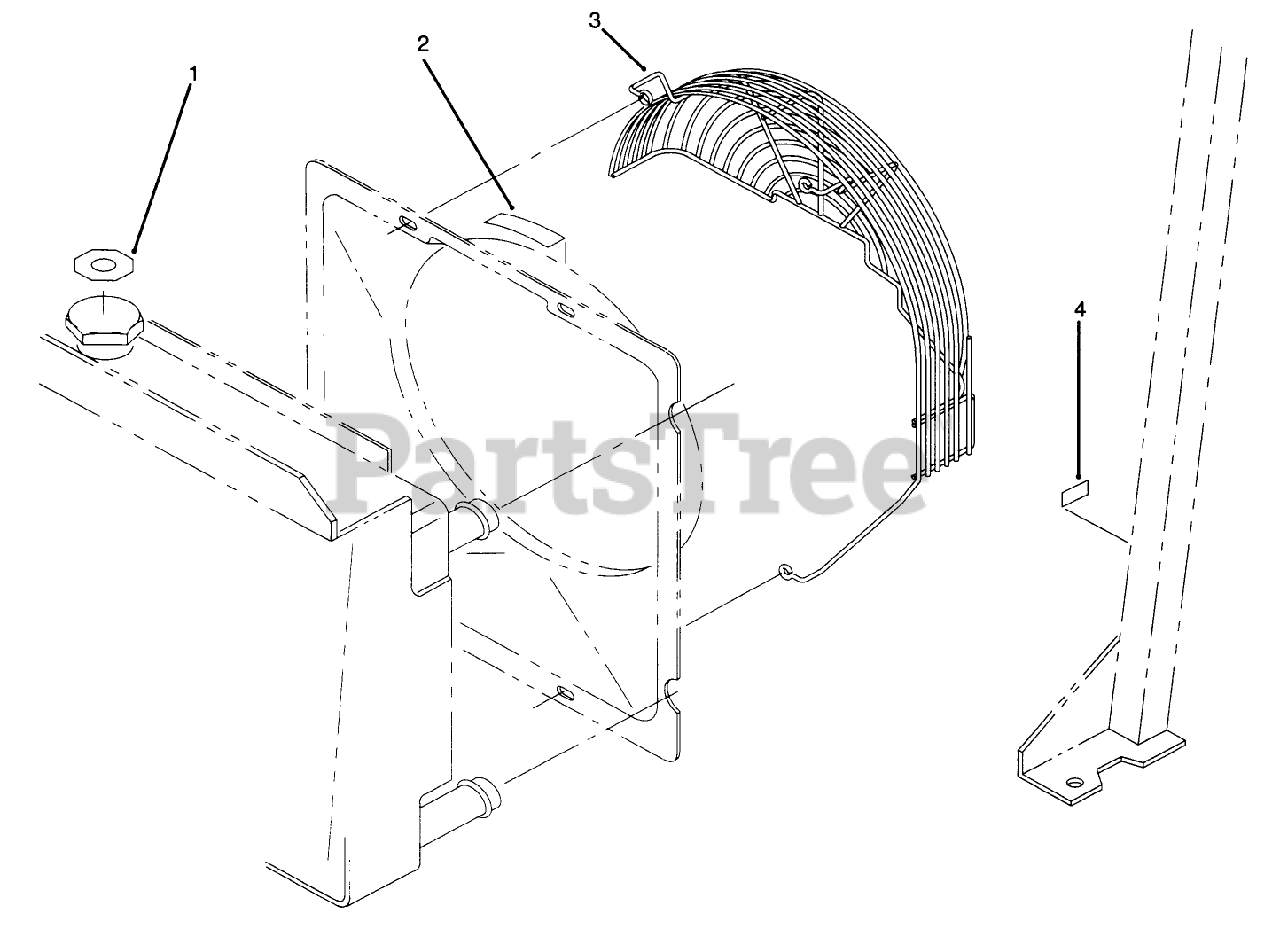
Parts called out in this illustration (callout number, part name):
1	DECAL-CAP, RADIATOR
2	DECAL-WARNING, FAN
3	GUARD - FAN
4	DECAL-BLANK
